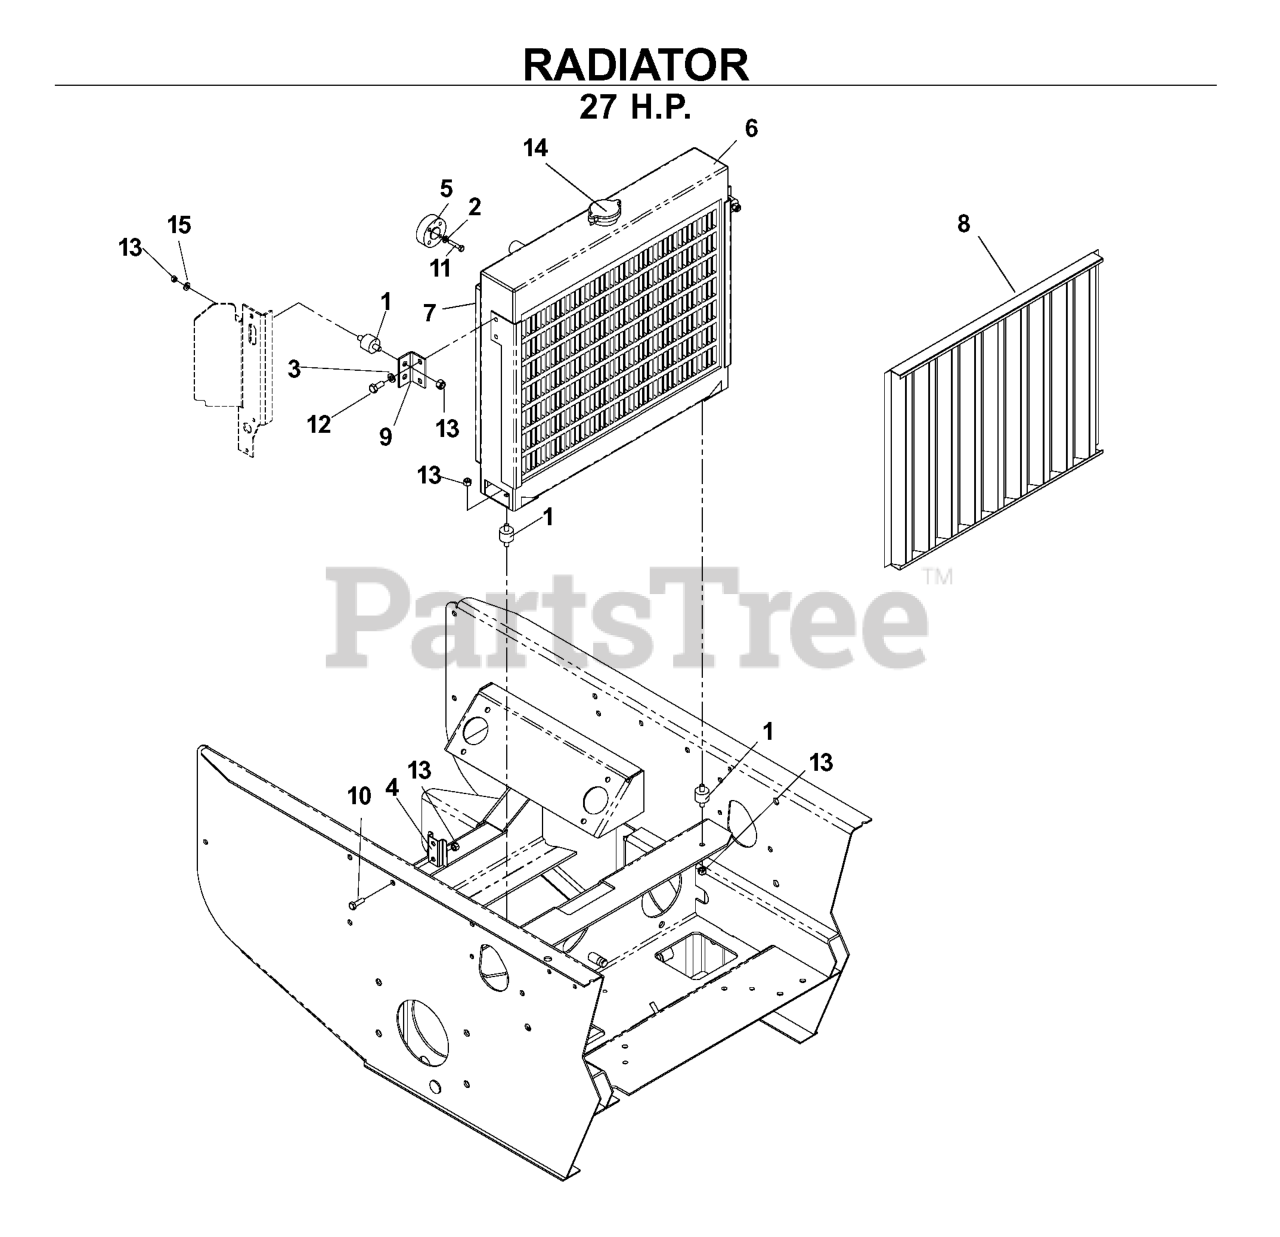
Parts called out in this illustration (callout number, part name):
2	LOCKWASHER 1/4"
3	WASHER.LOCK.HVY.HLCL.SPR.5/16
4	MOUNTING BRACKET
5	FAN SPACER
8	DEBRIS GUARD
9	BRACKET ISO
10	HCS 5/16C X 1
11	BOLT - M6-1.0 X 30MM GR 8
12	HCS 5/16C X 3/4
13	NUT 5/16 NYLOC
14	RADIATOR CAP
15	FLAT WASHER 5/16 SAE
539106326	LOWER HOSE
539106402	OVERFLOW TANK ASM
